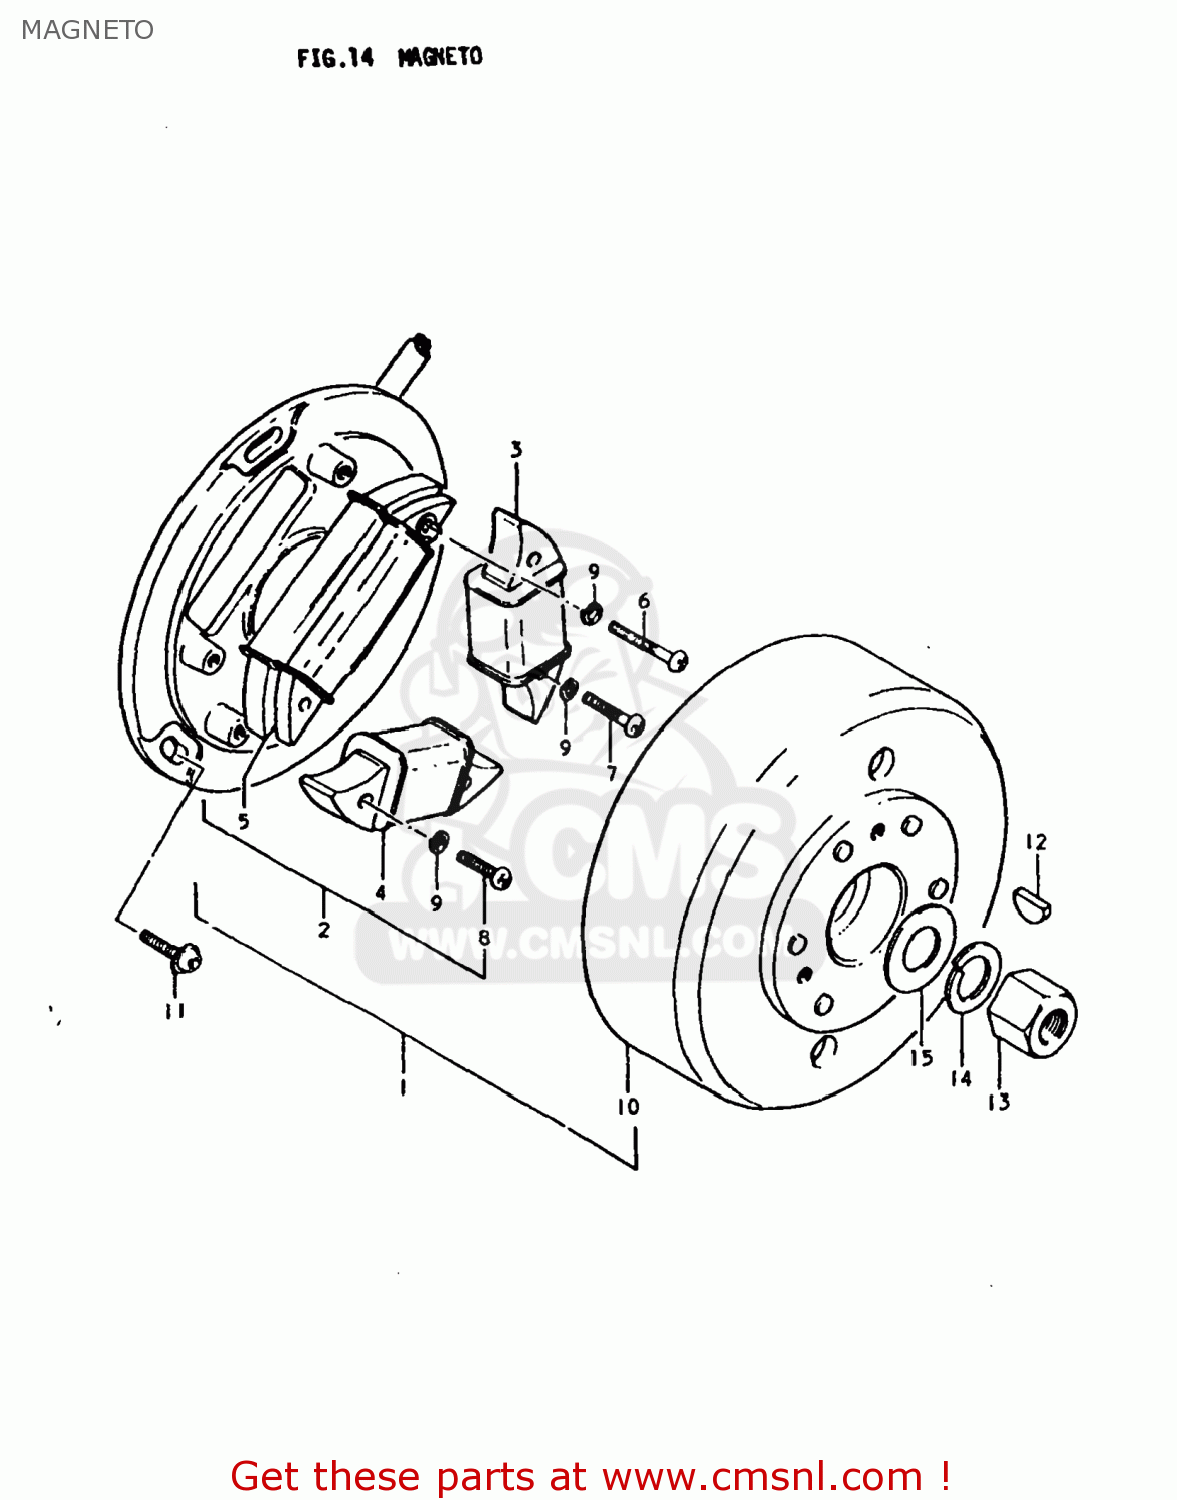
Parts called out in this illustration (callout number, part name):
1	MAGNETO ASSEMBLY
2	STATOR ASSEMBLY
3	COIL,CHARGE
4	COIL
5	COIL
6	COIL,PULSER
7	SCREW 5X35
8	SCREW 5X20
9	LOCK WASHER
10	ROTOR ASSEMBLY
